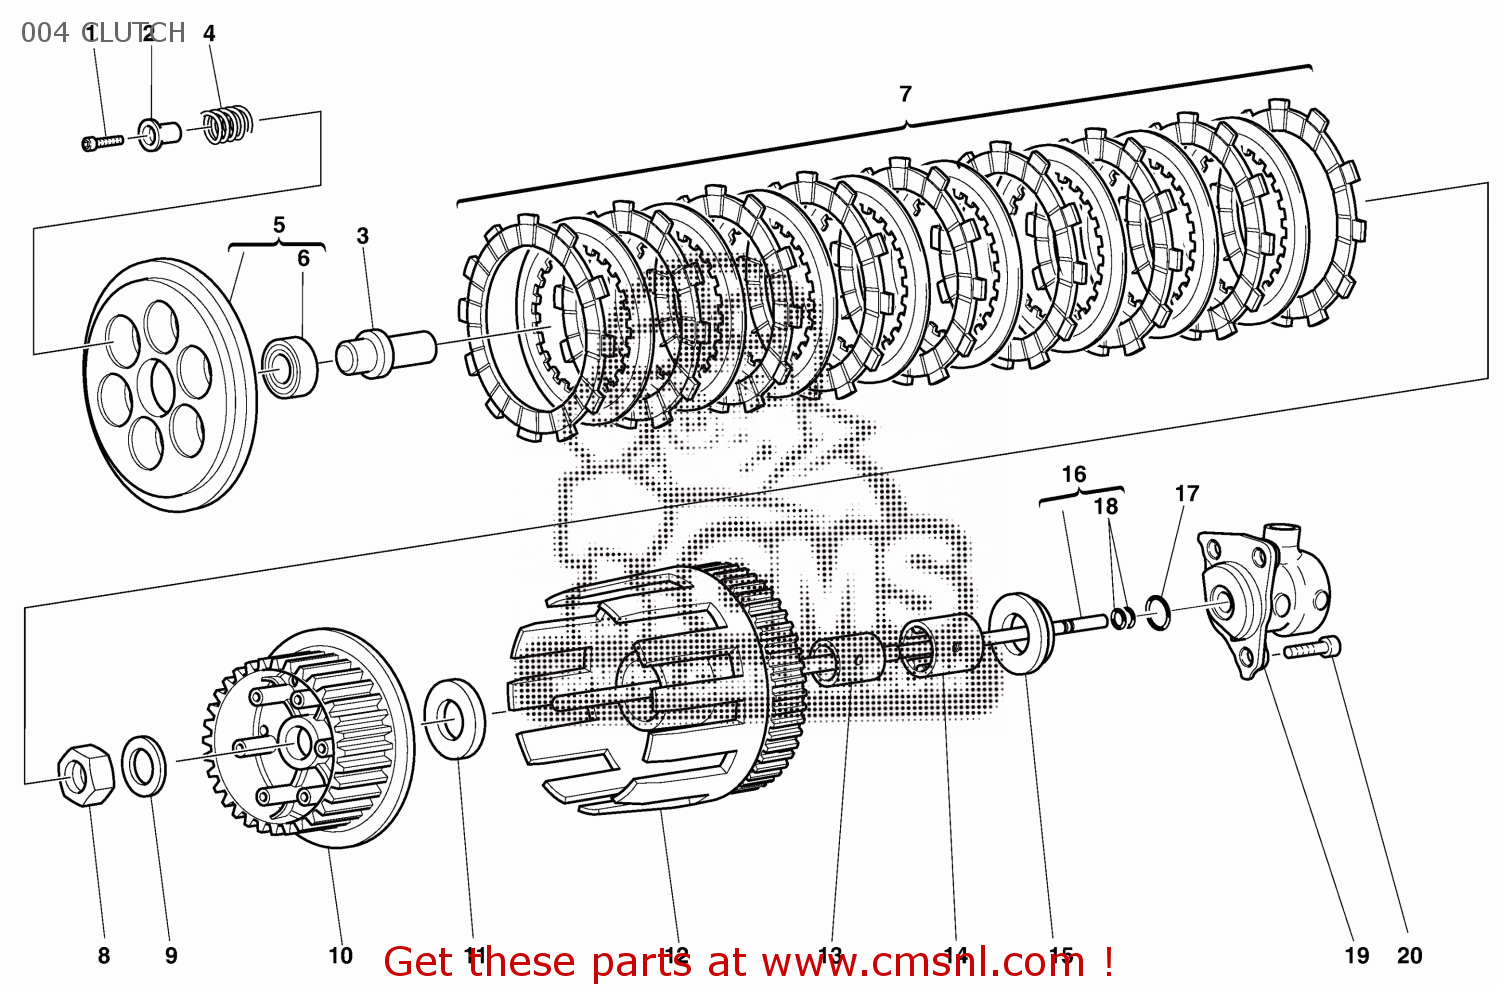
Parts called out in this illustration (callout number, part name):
1	SCREW M5X20
2	RETAINER
3	PIECE, CLUTCH PUSH
4	CLUTCH SPRING
5	DISK, CLUTCH PRESSURE
6	BALL BEARING 6003 TN9 C3
7	CLUTCH DISC SET
8	NUT
9	WASHER, LOCK
10	BOSS, CLUTCH
11	WASHER, THRUST
12	PRIMARY DRIVEN GEAR COMP.
13	BEARING INNER RING
14	BEARING, NEEDLE
15	SPACER
16	CLUTCH CONTROL ROD
17	O-RING
18	O-RING
19	CYLINDER, CLUTCH PRESSURE
20	SCREW TCEI M6X1.00X16
